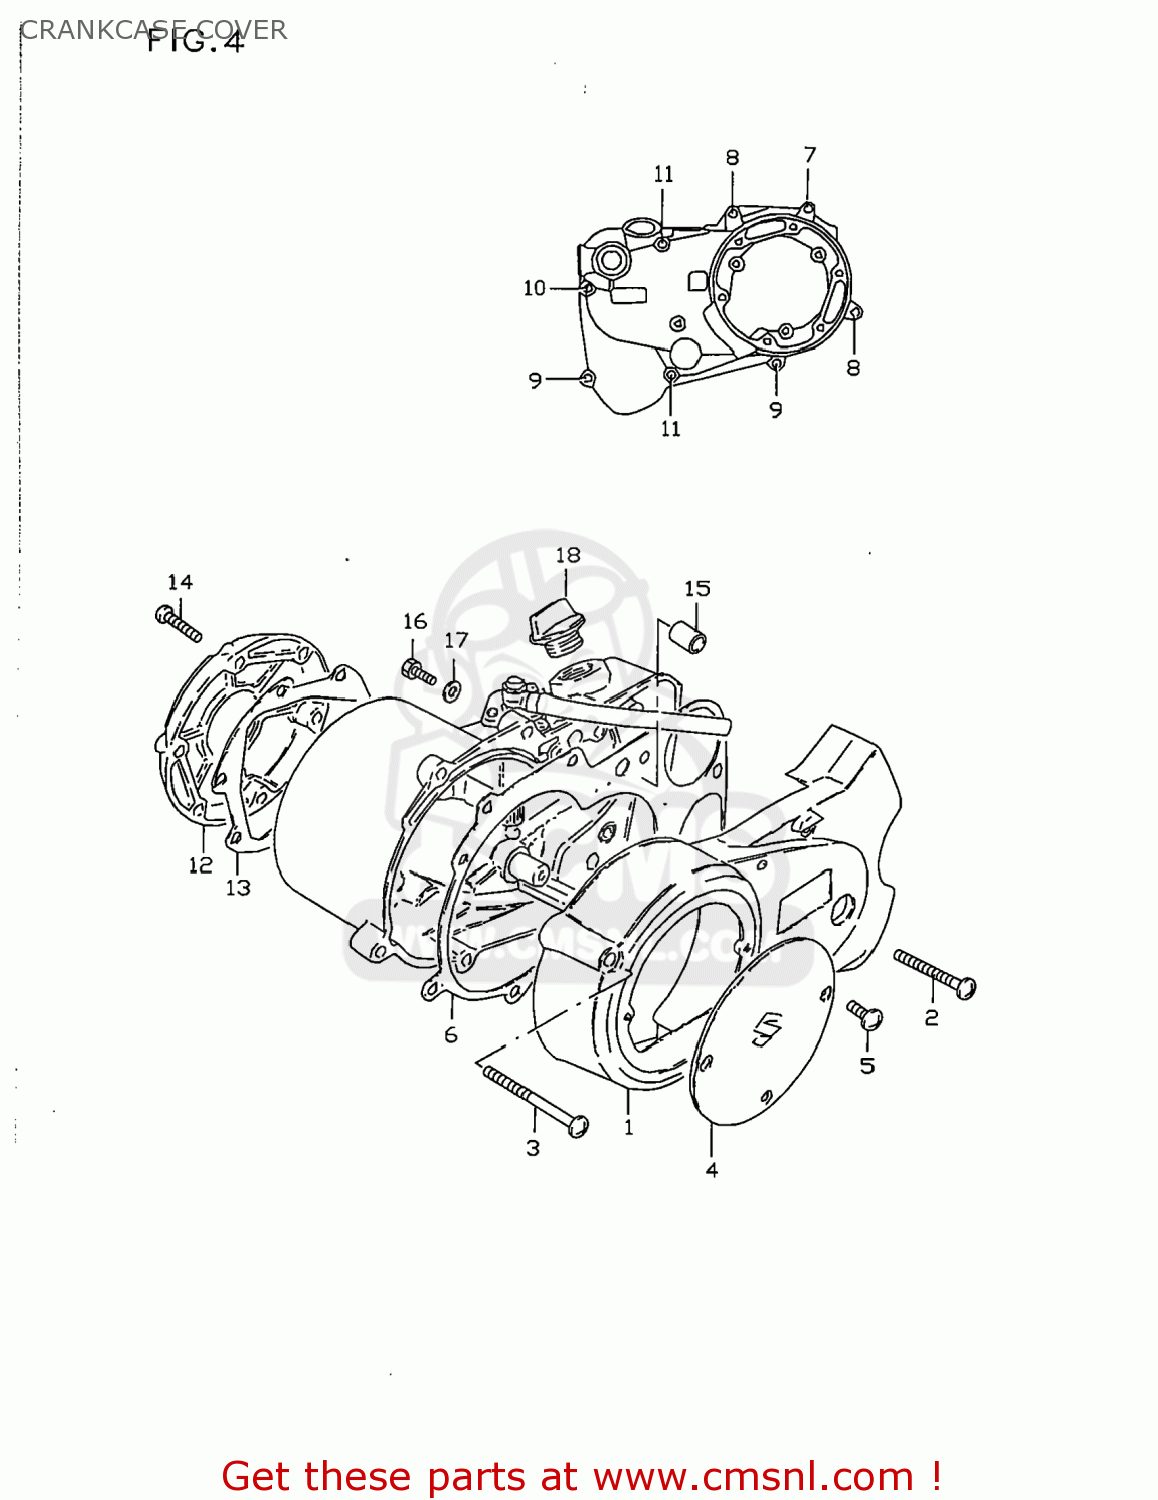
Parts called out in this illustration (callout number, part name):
1	COVER,MAGNETO
2	SCREW
3	SCREW
4	CAP,MAGNETO INSPECTION
5	SCREW 4X6
6	GASKET,CLUTCH COVER (NAS)
7	SCREW, 6X20
8	SCREW
9	SCREW 6X30
10	SCREW
11	SCREW
12	CAP,CLUTCH RELEASE ADJUST
13	GASKET,CL RLSE ADJ CAP (NAS)
14	SCREW, 6X20
15	PIN
16	SCREW(6X10)
17	GASKET(6.2X11X1) (NAS)
18	PLUG SET
